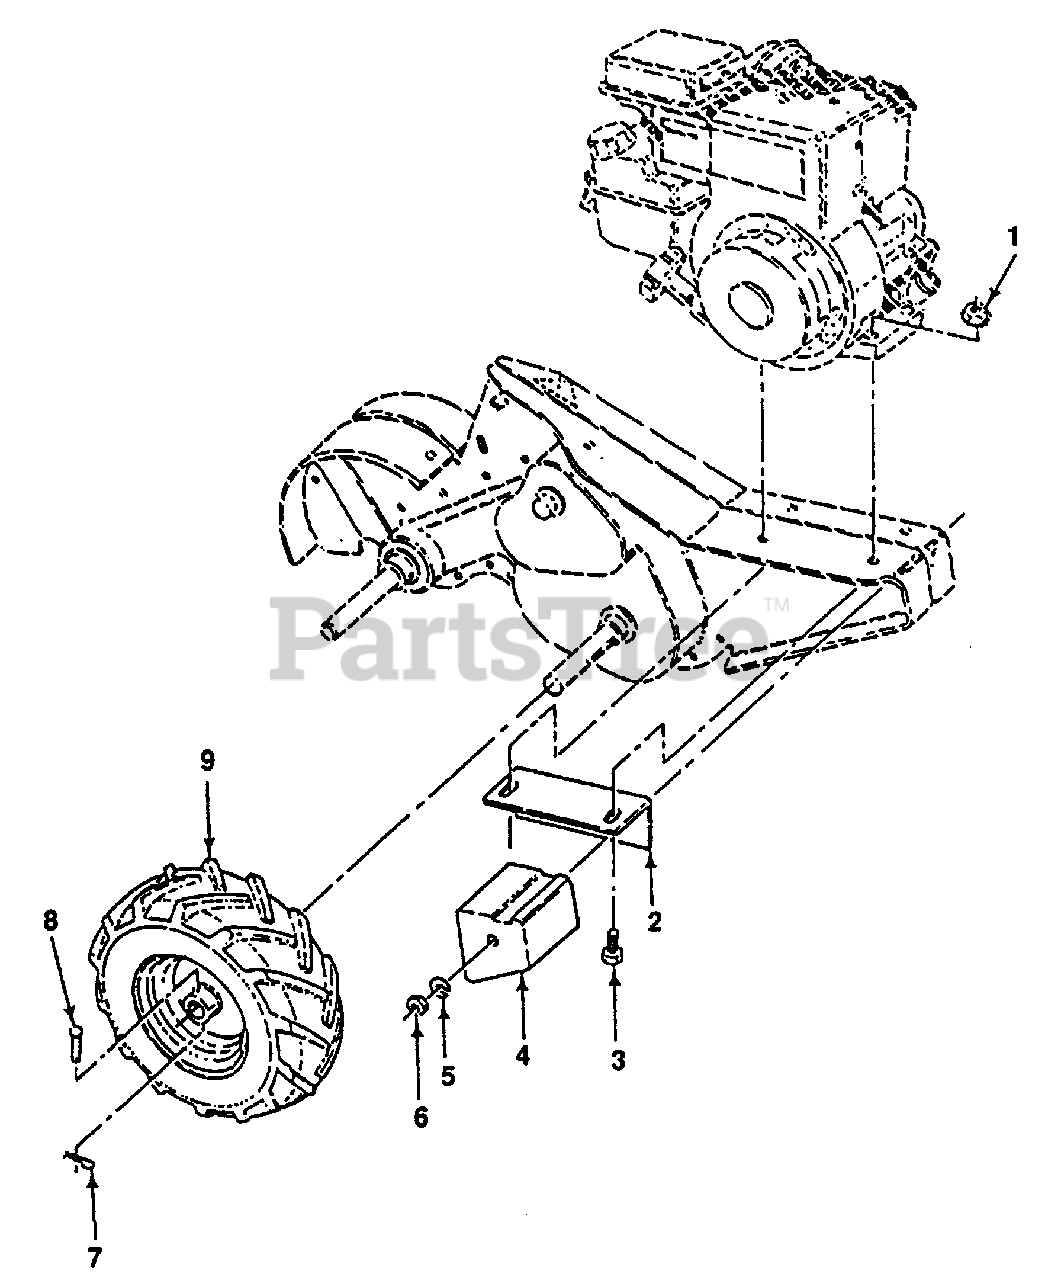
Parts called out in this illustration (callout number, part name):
1	Nut, Keps 5/16-18 (AYP part number)
2	Bracket, Reinforcment (AYP part number)
3	Bolt, Hex 5/16-18 x 1-1/2 (AYP part number)
4	Counter Weight, R.H. (AYP part number)
5	Washer, Lock 3/8 (AYP part number)
6	Nut, Hex 3/8-16 (AYP part number)
7	Clip, Hairpin (AYP part number)
8	Rivet, Drilled (AYP part number)
9	Tire (AYP part number)
